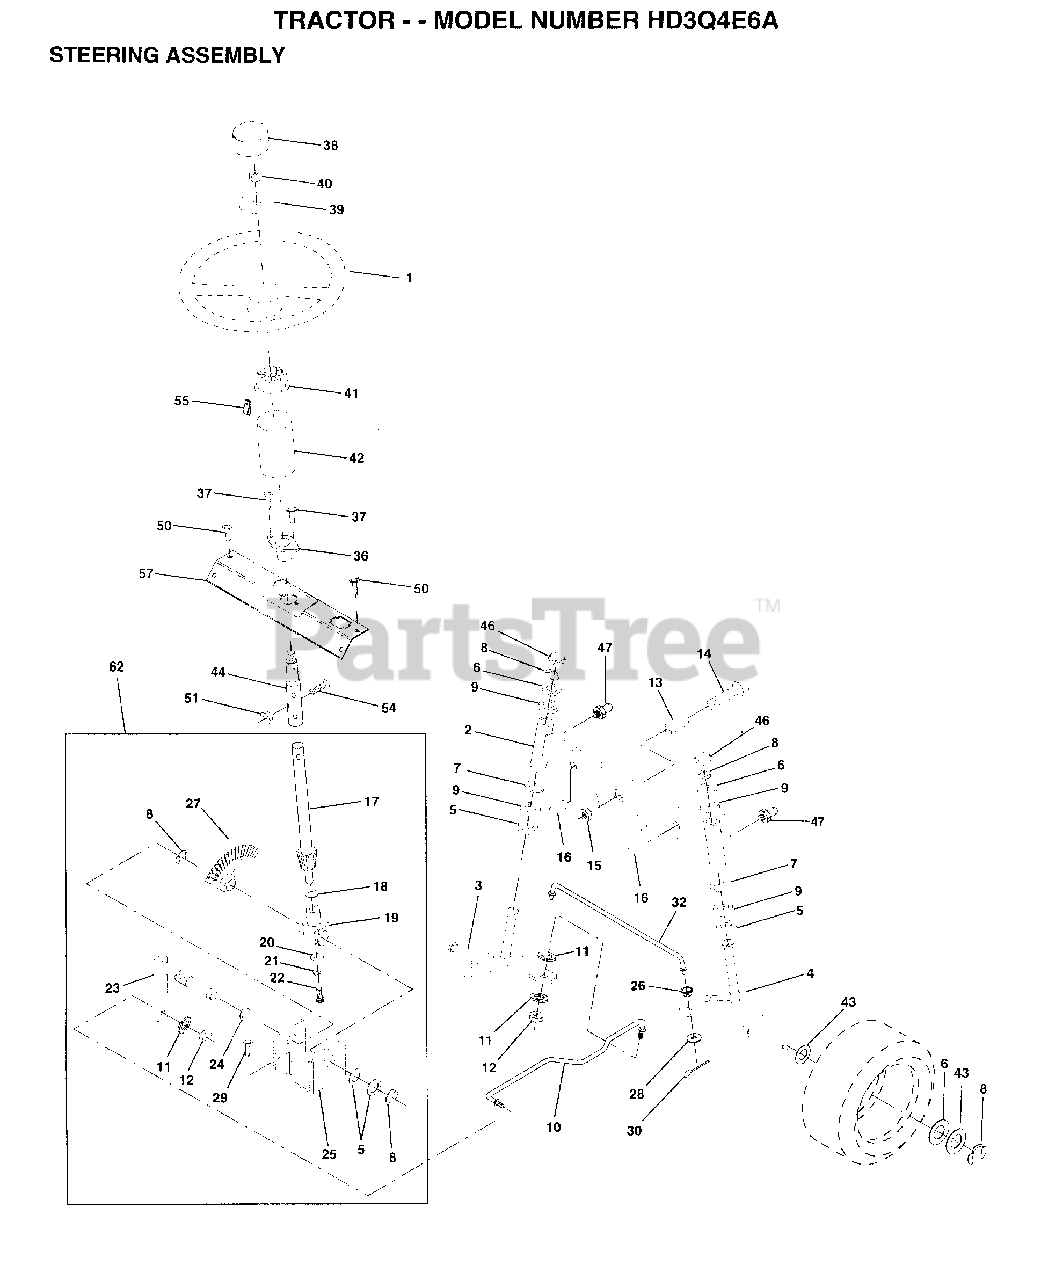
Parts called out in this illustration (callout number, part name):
1	WHEEL STR AYP BLK
2	AXLE ASM FRONT
3	SPINDLE LH
4	SPINDLE RH
5	WASHER .T
6	WASHER
7	WASHER
8	RING
9	COL. SRTG. BEAR.
11	LOCKWASHER
13	BEARING
14	BOLT HEX 5/8-11
15	"NUT-LOC,FLANGE LT"
16	AXLE PIN
17	SHAFT ASM STEERIN
18	THRUST WASHER
19	SUPPORT.SHAFT
21	LOCKWASHER
22	SCREW.SCKTHD.CAP
24	NYLINER T
25	"BRKT,STEERING"
26	BUSHING.DRAGLINK
27	GEAR SECTOR
28	WASHER
29	SCREW
30	COTTER PIN
32	TIE ROD
38	CAP STEER AYP
39	WASHER T
40	GRIPCO NUT
41	ADAPTER-WHEEL LT
42	BOOT SHAFT STEER
43	WASHER
46	CAP
47	ZERK M
50	SCREW HEX CRT
51	NUT
54	BOLT
55	CLIP TINNERMAN
57	SUPPORT SHAFT STR
